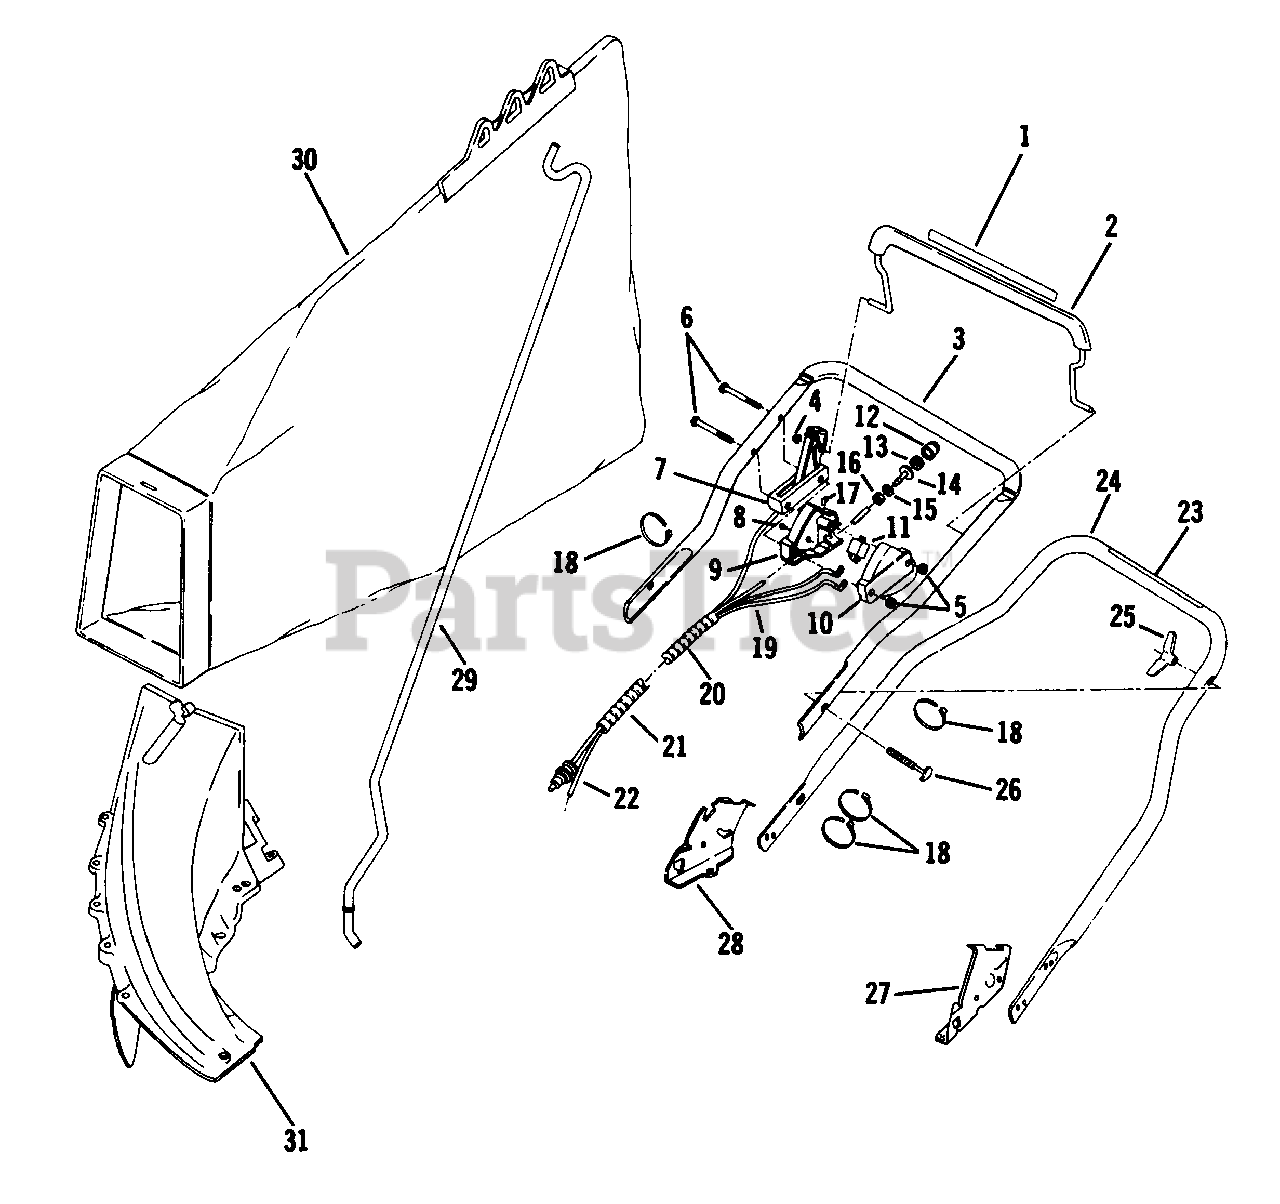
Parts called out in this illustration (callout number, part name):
1	Decal-Blade Control
2	Control Lever Assembly
3	Upper Handle and Grip Assembly
4	Pushnut
5	Nut-Hex-Centerlock
6	Screw
7	B.B.C. Control Assembly
8	Screw
9	Console-R.H.
10	Console-L.H.
11	Switch Assembly
12	Primer Bulb
13	Filter
14	Primer Base
15	Washer
16	Locknut
17	Decal
18	Tie Strap
19	Wire Harness Assembly
20	Spiral Tubing
21	Spiral Tubing
22	Tubing
23	Decal-Starting Inst.
24	Handle-Bottom
25	Knob
26	Screw-Folding Handle
27	Handle Bracket-L.H.
28	Handle Bracket-R.H.
29	Rod-Grass Bag
30	Bag Assembly
31	Chute Assembly
